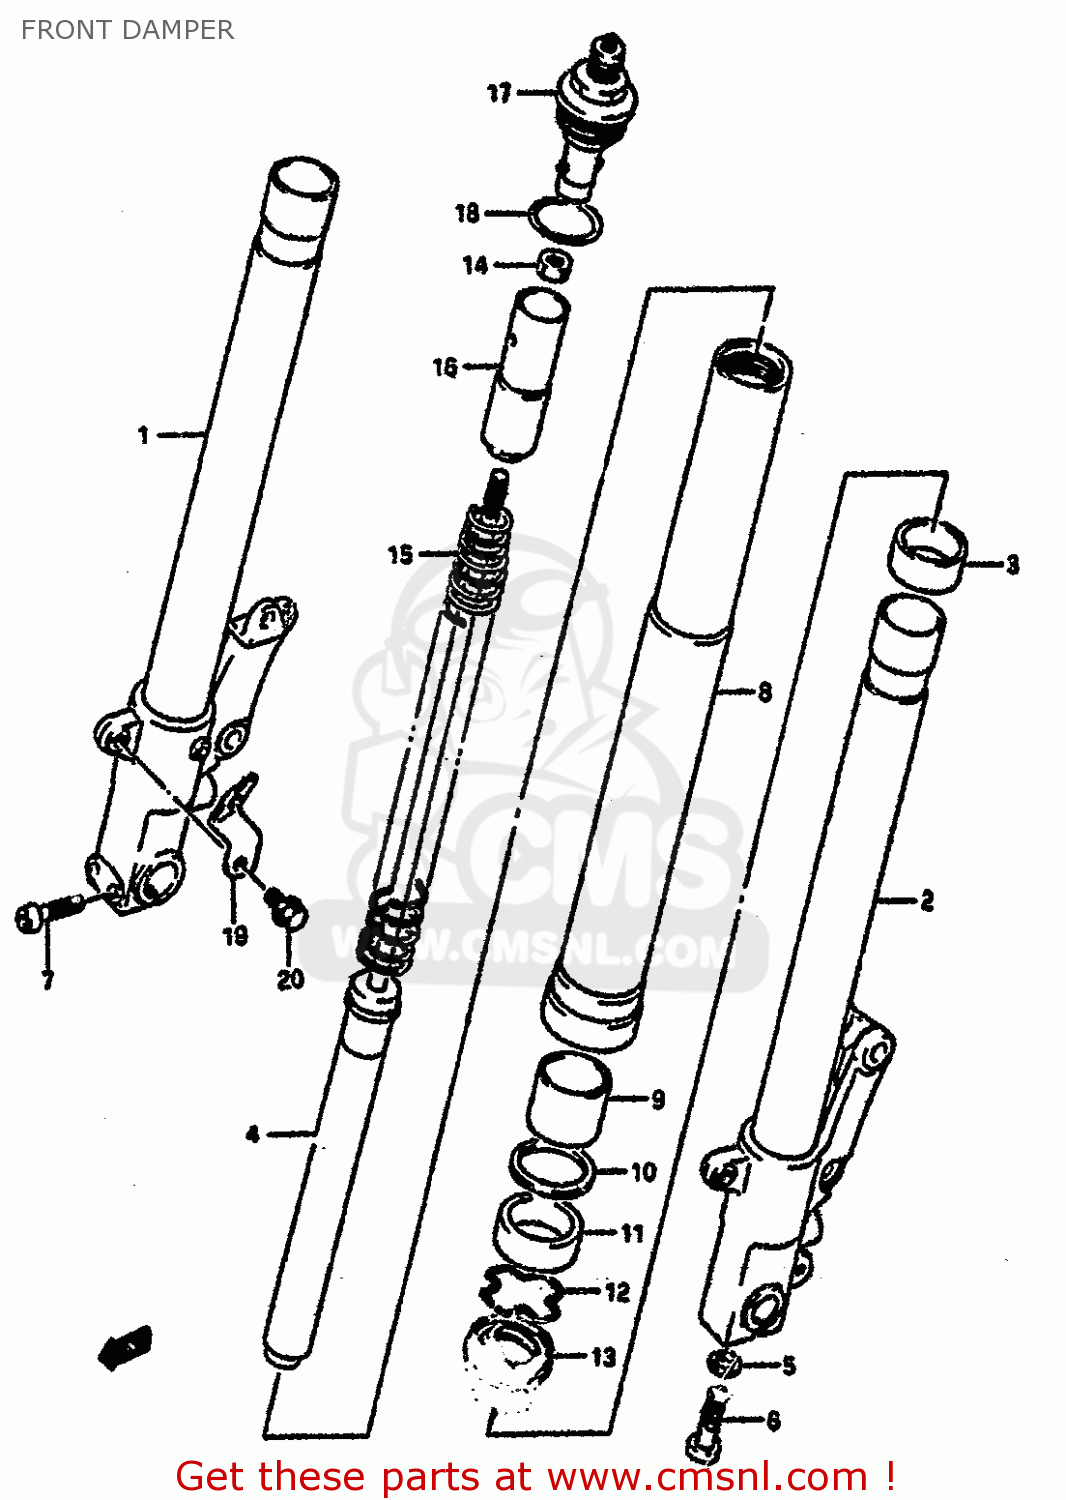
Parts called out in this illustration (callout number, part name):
1	TUBE,INNER,R
2	TUBE,INNER,L
3	PISTON
4	CYLINDER ASSY
5	GASKET,CYLINDER (NAS)
6	BOLT,OIL LOCK PIECE,12X22
7	BOLT
8	TUBE,OUTER
9	10
10	WASHER,FORK OIL SEAL
11	OIL SEAL,FRONT FORK
12	RING,OIL SEAL STOPPER
13	SEAL,DUST
14	NUT,ROD
15	SPRING,MAIN
16	SPACER,SPRING
17	CAP ASSEMBLY,FORK
18	O RING
19	PLATE,FRONT FENDER,LEFT
20	BOLT 8X12
